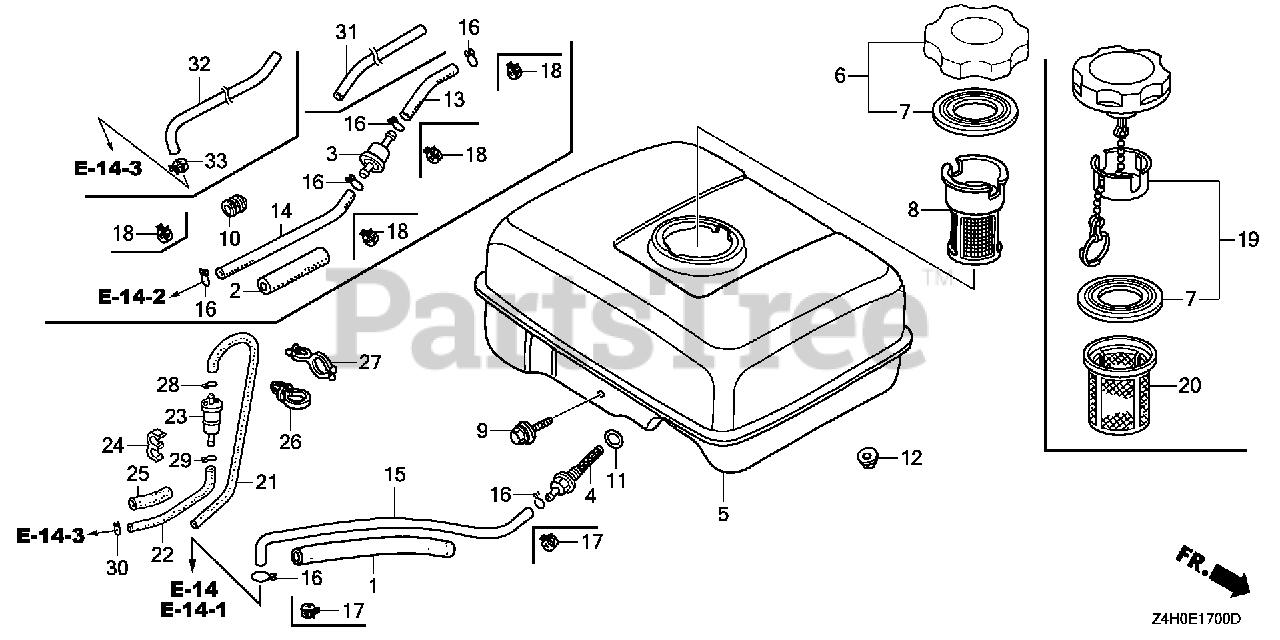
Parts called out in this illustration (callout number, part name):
21	TUBE A, AIR VENT
23	STRAINER, FUEL
24	CLAMP, TUBE (7.5X2)
28	CLIP, TUBE (B8)
29	CLIP, TUBE (B10)
30	CLIP, TUBE (C9)
